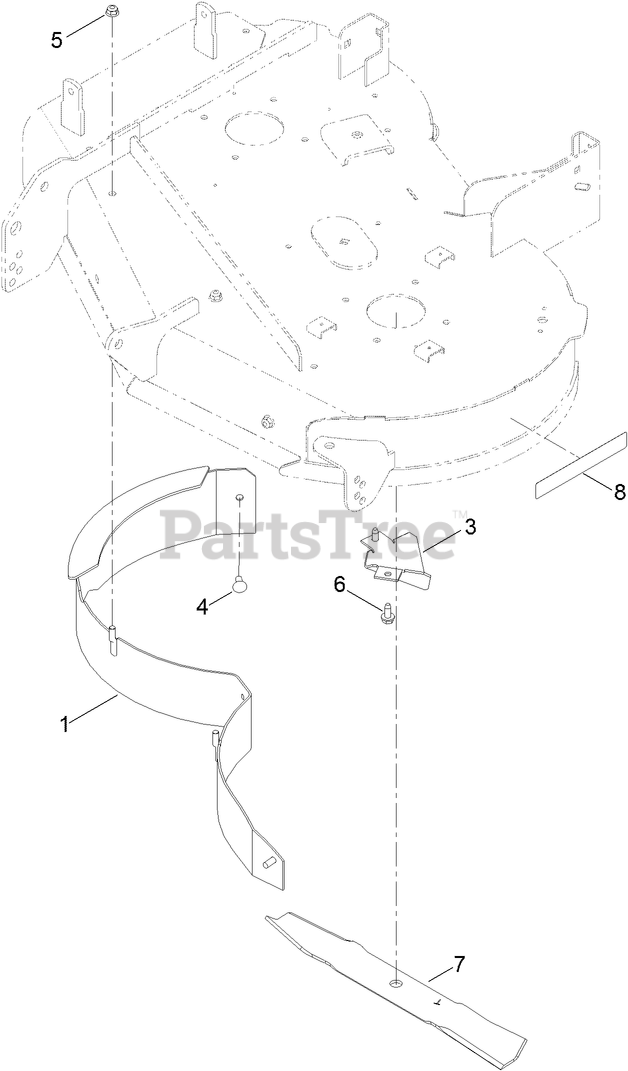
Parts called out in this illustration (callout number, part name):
1	BAFFLE ASM
3	KICKER-FLANGED
4	BOLT-CARR
5	NUT-HF, NI
6	SCREW-HWHTF
7	BLADE-MULCH, 17.50 INCH
8	DECAL-RECYCLER
